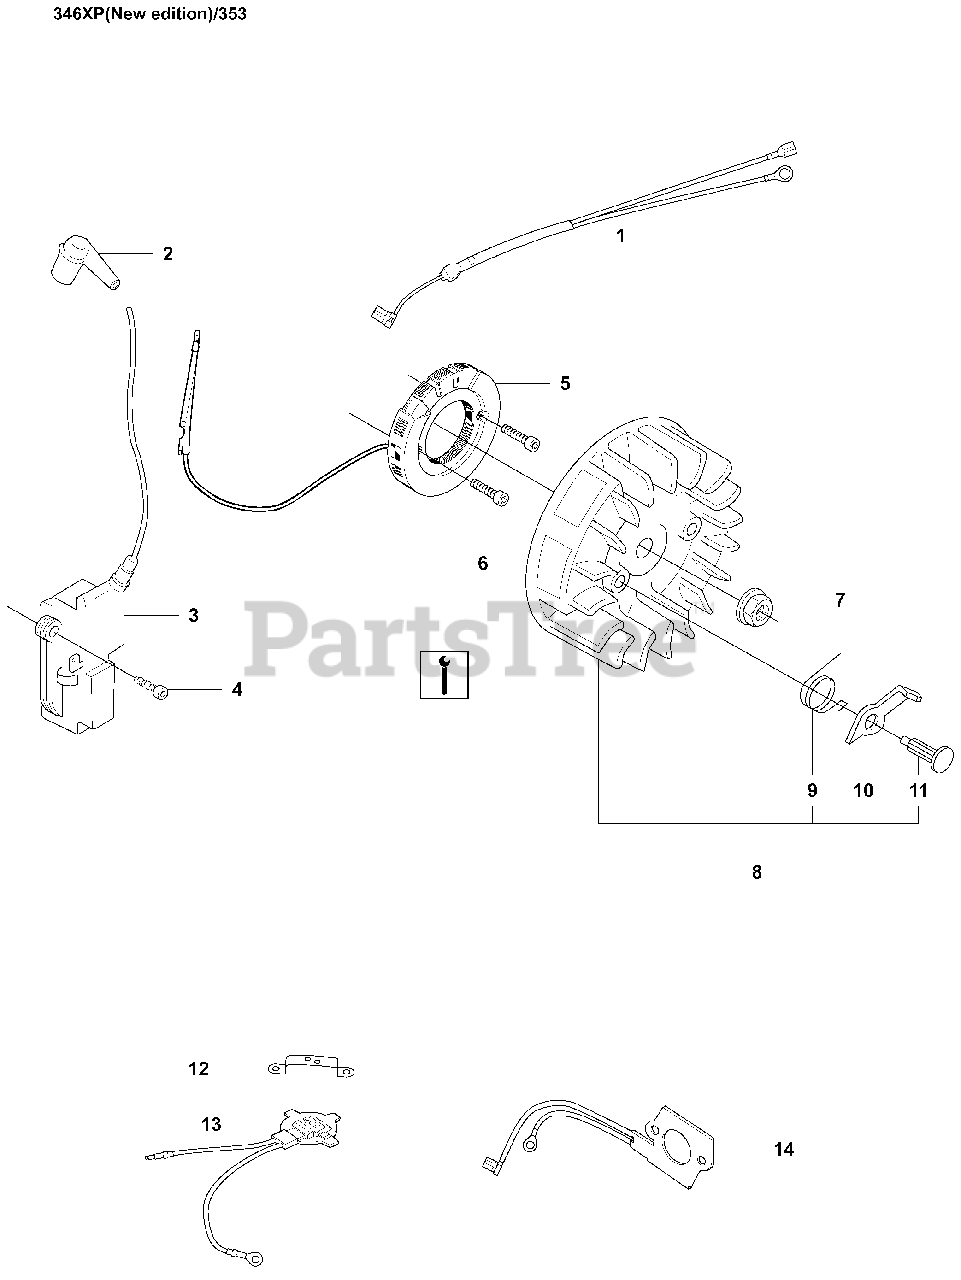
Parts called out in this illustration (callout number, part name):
1	CABLE ASSY
2	SPARK PLUG CONN. KIT
3	IGNITION MODULE
3	%IGNITION MODULE
5	GENERATOR
7	NUT W/ WASHER
8	FLYWHEEL (G)
8	RP FLYWHEEL
9	%SPRING, STARTER CATCH
10	PAWL
11	RIVET
12	BRACKET
13	THERMOSTAT
14	ELEMENT
